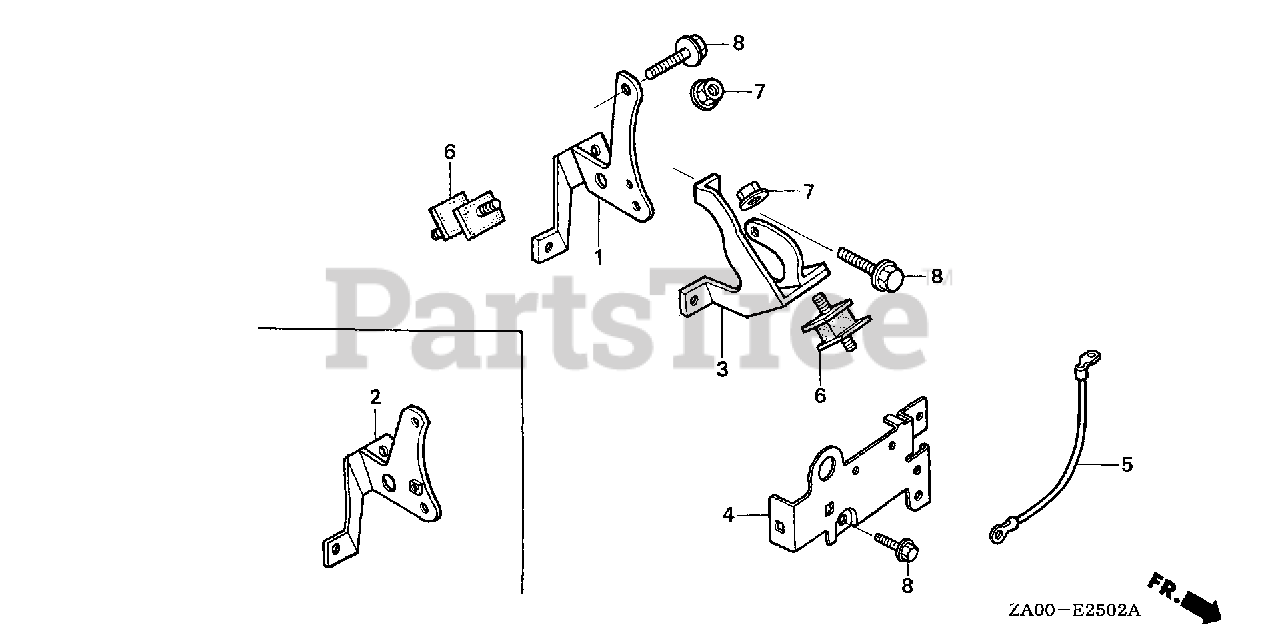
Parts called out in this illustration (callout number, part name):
1	STAY, R. ENGINE MOUNTING
3	STAY, L. ENGINE MOUNTING
4	HOOK, ENGINE
5	CABLE, BATTERY GROUND
6	RUBBER, ENGINE MOUNTING
7	NUT, FLANGE (10MM)
8	BOLT, FLANGE (8X20)
